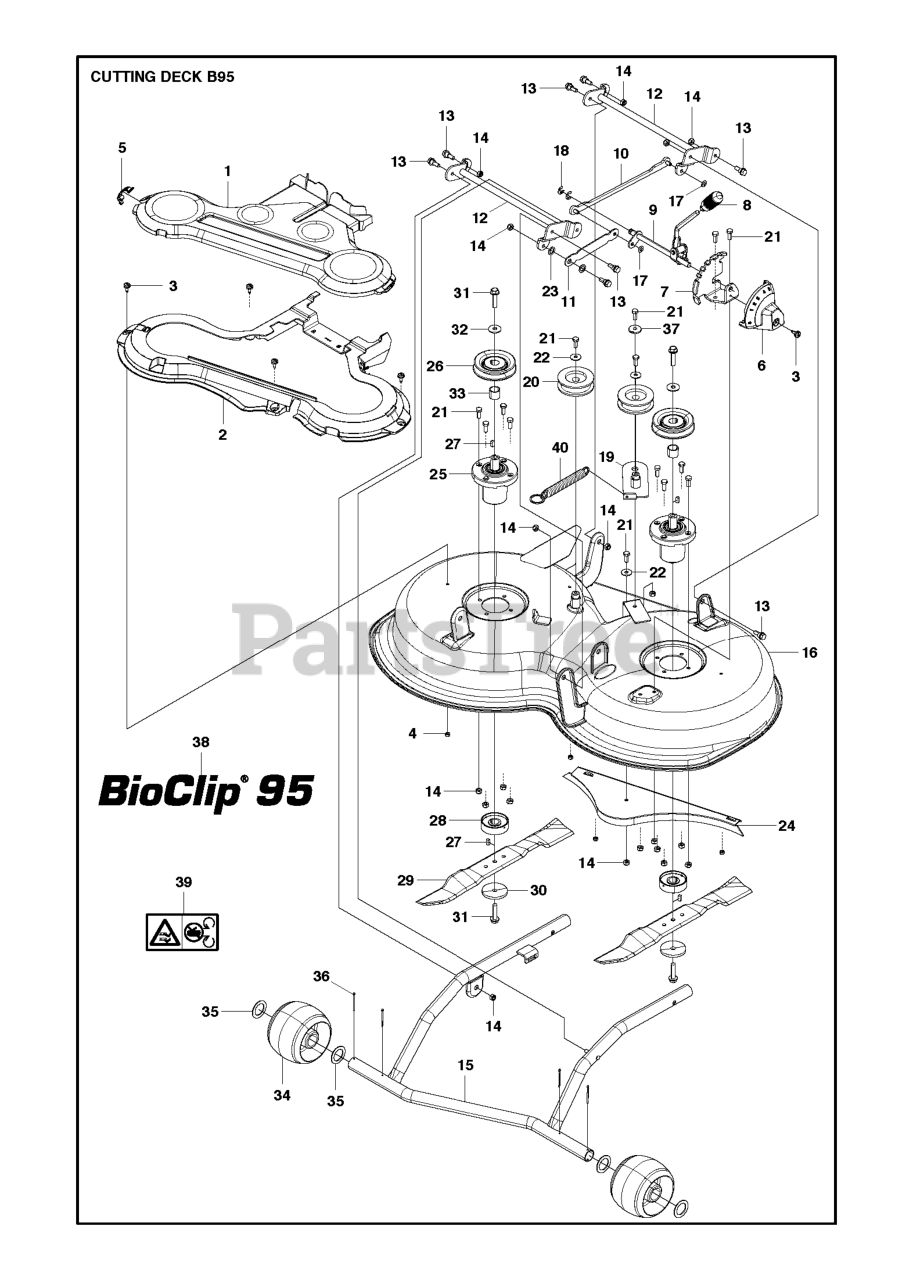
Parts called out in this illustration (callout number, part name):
1	FILTER HEAD
2	HYDRAULIC OIL FILTER
3	HYDRAULIC CAP
4	HG_PUMP
6	OIL FILTER BRKT
7	FITTING, STRAIGHT F6400-8-8-0
8	STRAIGHT FITG
9	ELBOW, F6801-6-6-0 90 DEGREE
10	HYDRAULIC HOSE
12	TEE ASSEMBLY
13	TEE ASSEMBLY
15	NUT 9/16-18 JIC CAP
16	HCS 1/4C X 5/8
17	HCS 1/4C X 3/4 HCS
18	LOCKWASHER 1/4"
19	NUT.1/4-20.HEX.NYLOC.ZD
20	WASHER 1/4 FLAT
27	PUMP BELT
28	KEY 5 MM SQ X 25 MM
29	SCREW 5/16C X 5/8 SQ HEAD
30	PUMP LEVER
31	5/16C X 5/8 "V" POINT
33	NUT 3/8C WHIZ
34	NUT 3/8-16 NYLOC
35	HCS 3/8C X 2
36	TORSION SPRING
37	BUSHING, IDLER FLANGE
38	NUT 3/8C CENTERBLOCK
39	HCS 3/8-16 X 1 3/4 GR5
40	WASHER 3/8 FLAT
41	IDLER PULLEY
42	NUT 1/2-13 HEX NYLOC ZD
44	PIVOT BUSHING
45	IDLER ARM WLDT
46	ZERK
47	WASHER 1/2 FLAT
48	HCS 1/2C X 3 1/4
